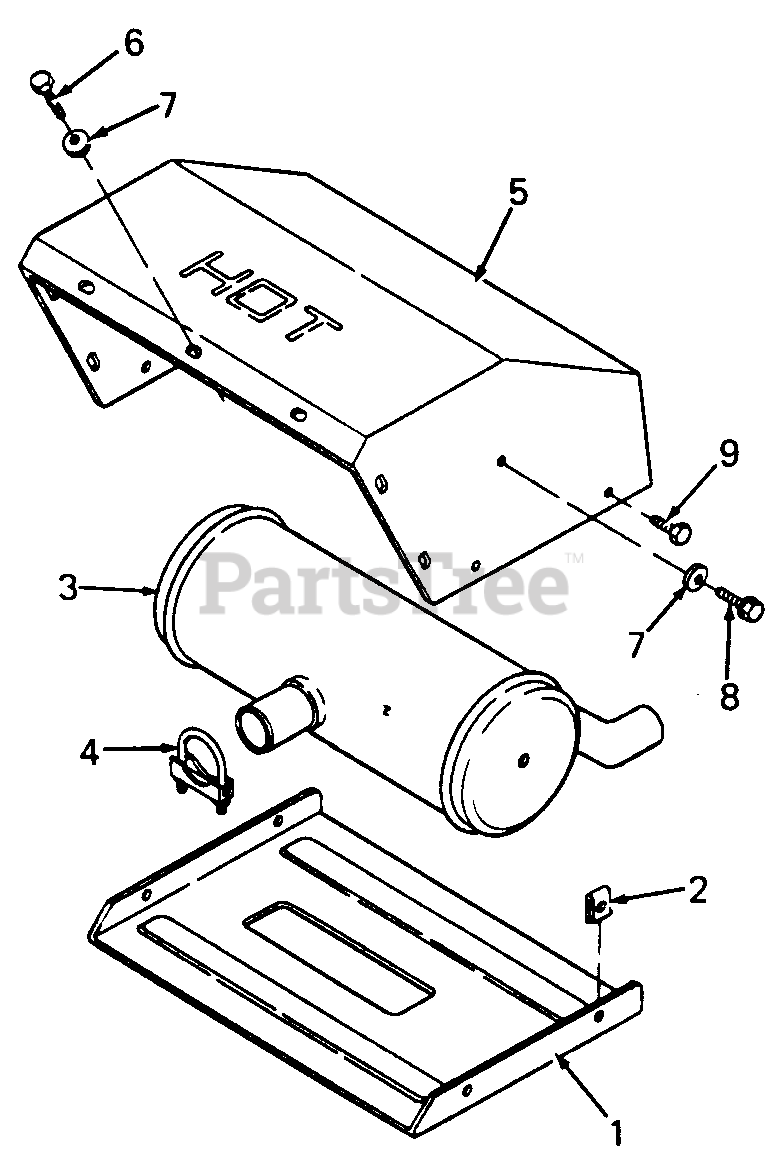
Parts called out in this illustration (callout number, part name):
1	Shield, Bottom Heat
2	Nut, U-Type Speed, 1/4-20
4	Clamp Assy, Muffler
7	Washer, Bell, .265 X .75 X .062 Thk
8	Screw, Hex Cap, M6-1.0 X 20 mm Lg GR10.9
9	Screw, Hex Wash Hd TT-Tap, 1/4-20 X .50 Lg
